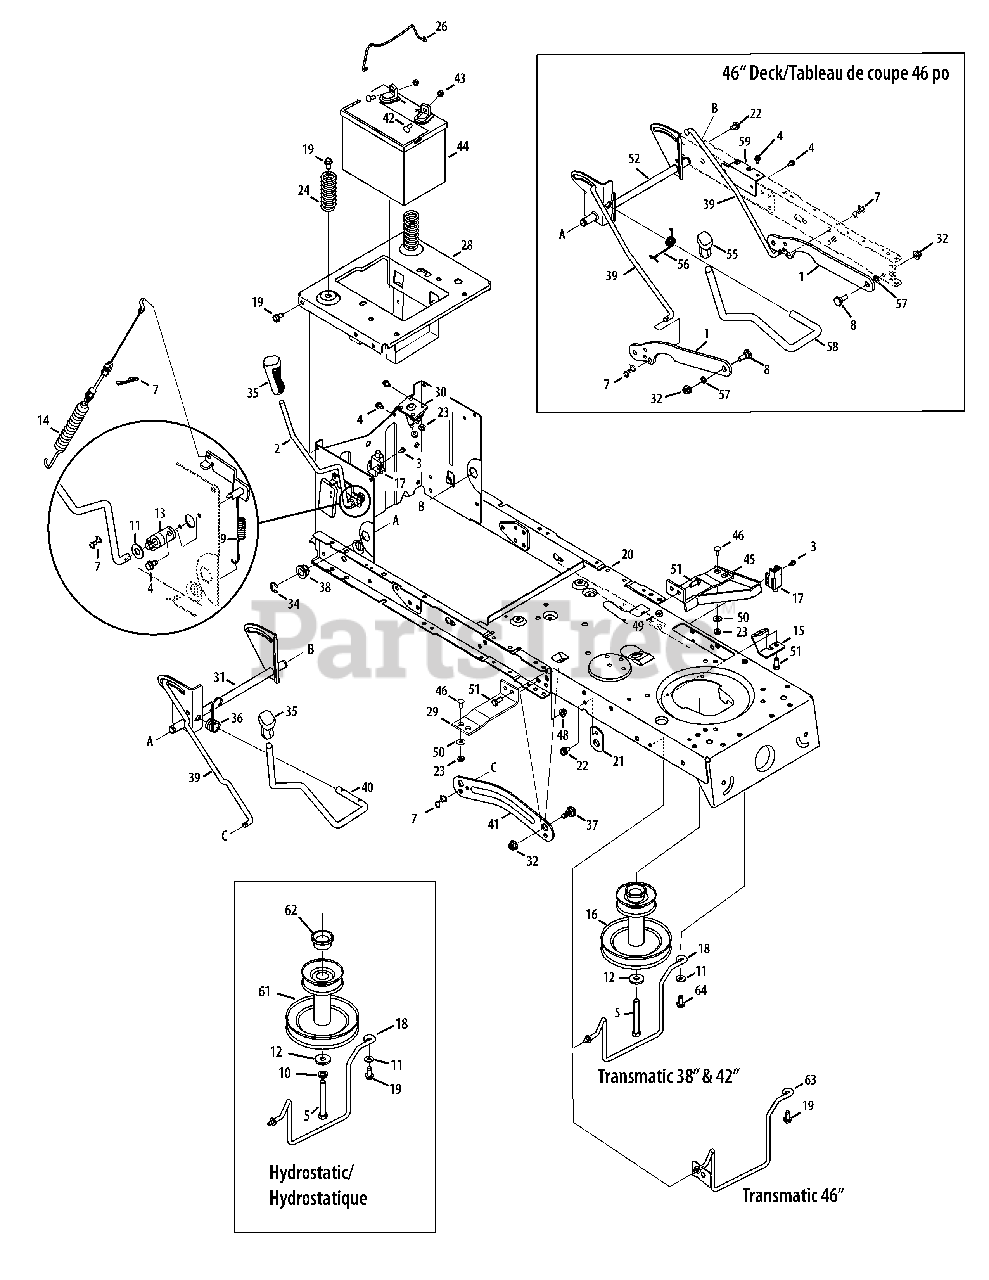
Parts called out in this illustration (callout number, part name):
1	Deck Lift Link (46")
2	PTO Handle - Black
3	Shoulder Scr #10-16 x .50" Lg.
4	Hex Wash S-Tapp Scr 1/4-20 x .50
5	Hex Hd. Cap Scr. 7/16-20 x 3.25 Gr. 5 (38/42")
7	Bow Tie Cotter Pin
8	Shoulder Screw .5 x .270 : 3/8-16
9	Extension Spring
10	Lockwasher 7/16 ID
11	Flat Washer .385 ID x .87 OD x .06 (38/42")
12	Flat Washer .450 x 1.25 x .164
13	PTO Bearing
14	Deck Engagement Cable
15	Frame Support Bracket - Black
16	Engine Pulley 3.39 x 6.12 dia. (38/42")
17	Interlock Switch
18	Belt Keeper Rod (38" Deck)
19	S-Tapp Scr 5/16-18 x .75
20	Frame - Black
21	Pedal Support Bracket - Black
22	Hex Wash HD TT Scr 5/16-18 x .625
23	Hex L-Flanged Nut 1/4-20 Gr. F, Nylon
24	Compression Spring 1.28 x 3.125
26	Battery Hold Down Rod
28	Seat Frame Bracket - Black
29	Running Board Bracket - Black
29	Running Board Bracket - Green
30	Solenoid
31	Lift Shaft (38" & 42")
32	Flange Lock-Nut 3/8-16 Gr. F, Nylon
34	"E" Ring .625 Dia.
35	Handle Grip
36	Torsion Spring (38" & 42")
37	Shoulder Screw .625 x .175, 3/8-16
38	Hex Flange Bearing .630 ID
39	Lift Rod
40	Deck Lift Handle(38"")
40	Deck Lift Handle(42")
41	Deck Lift Arm RH - Black
41	Deck Lift Arm RH - Green
41	Deck Lift Arm LH - Black
41	Deck Lift Arm LH - Green
42	Hex Flg. Scr. 1/4-20 x .75 Gr. 5
43	Sems Hex Nut 1/4-20
44	Battery 245 CCA (Dry)
45	Support Bracket Ass’y - Black
45	Support Bracket Ass’y - Green
46	Carriage Bolt 1/4-20 x .75
48	Hex L-Flg Nut 5/16-18 Gr. F, Nylon
49	Hex L-Nut 5/16-18
50	Flat Washer .28 x .74 x .063
51	Hex Screw 5/16-18 x .75
52	Lift Shaft (46" only)
56	Torsion Spring (46")
57	Flat Washer .395 x .62 x .063
58	Deck Lift Handle (46")
59	Brace Bracket
61	Engine Pulley 3.39 x 6.12 dia. (38/42")
61	Engine Pulley 3.39 x 6.12 dia. (46")
62	Spacer 1.0 x 1.4 x .825
63	Belt Keeper Rod (46" Deck)
64	Scr 5/16-18 x .75
